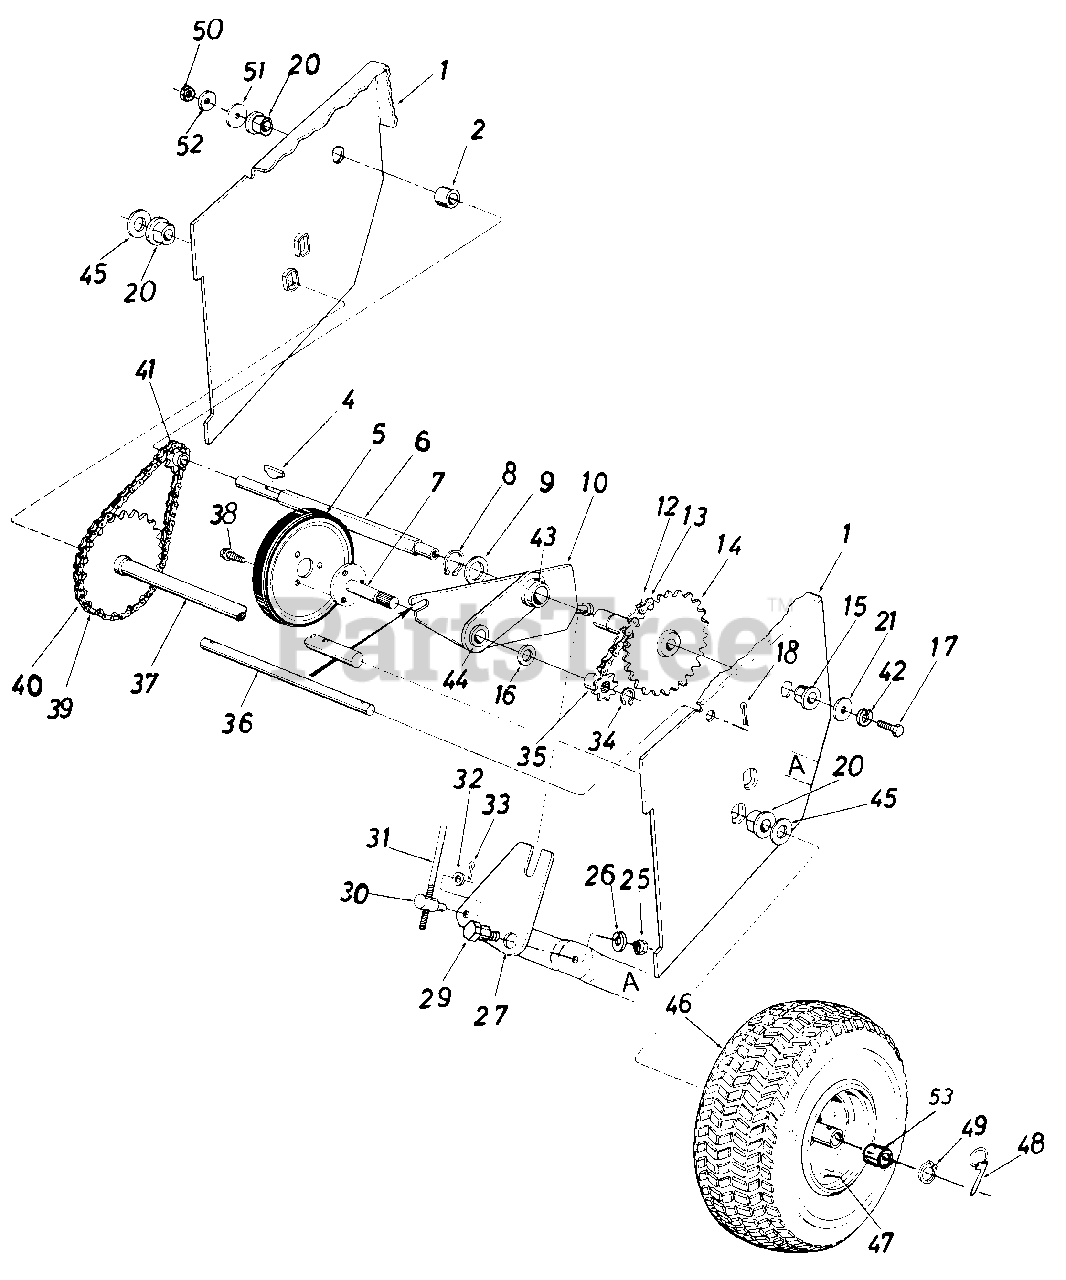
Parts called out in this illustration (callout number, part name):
1	Frame Ass'y.
2	Spacer.50" I.D. x .75" O.D. x .78" Lg.
4	#4 Hi-Pro Key 3/32 x 5/8" Dia.
5	Friction Wheel Ass'y.
7	Friction Wheel Mounting Plate Ass'y.
8	Snap Ring 1.00" Dia. Shaft
9	Fl-Wash. 1.00" x 1.63" O.D. x .03
10	Sliding Bracket Ass'y.
12	#41 Chain 1/2" Pitch x 35 0 Links
13	Master Link for #41 Chain
14	32 Teeth Sprocket Ass'y.
15	Hex Flange Brg. .630" I.D.
16	Fl-Wash. .62" I.D. x 1.00" O.D. x .06
17	Hex Lock Bolt 5/16-18 x .62" Lg.
18	Cotter Pin 3/32" Dia. x .75" Lg.*
20	Flange Brg. w/ Flats .755" I.D.
21	Fl-Wash. .34" I.D. x 1.12" O.D. x .125
25	Hex Jam Nut 3/8-16 Thd.
26	L-Wash. 3/8" I.D.*
27	Shifting Linkage Bracket
29	Shld. Bolt .625" Dia. x .170" Lg.
30	Adjustment Ferrule
31	Shifting Rod 5/16" Dia. x 32.50" Lg.
32	Fl-Wash. .34" I.D. x .64" O.D, x .06
33	Cotter Pin 3/32" Dia. x .75" Lg.*
34	Snap Ring .562" Dia. Shaft
35	Sprocket 7 Teeth x .50" Pitch
36	Shaft .50" Dia. x 9.50" Lg.
37	32 Teeth Wheel Axle Ass'y.
38	Hex Wash. Hd. Self-Tap Scr. 5/16-24 x .50" Lg.
39	#420 Chain 112" Pitch x 39 Links
40	Master Link for #420 Chain
41	8 Teeth Center Sprocket
42	L-Wash. 5/16" I.D.
43	Plastic Bearing
44	Bronze Bearing
45	Fl-Wash. .76" I.D. x 1.49 O.D.
46	Wheel Ass'y. Comp.
47	Air Valve
48	Klick Pin
49	Snap Ring .75 Dia.
50	Hex Ins. L-Nut 1/2-20 Thd.
51	Fl-Wash. .53 0 I.D. x 1.25 O.Dx .1 0
52	Bell-Wash. .50 I.D. x 1.0 O.Dx .075
53	Sleeve Bearing
